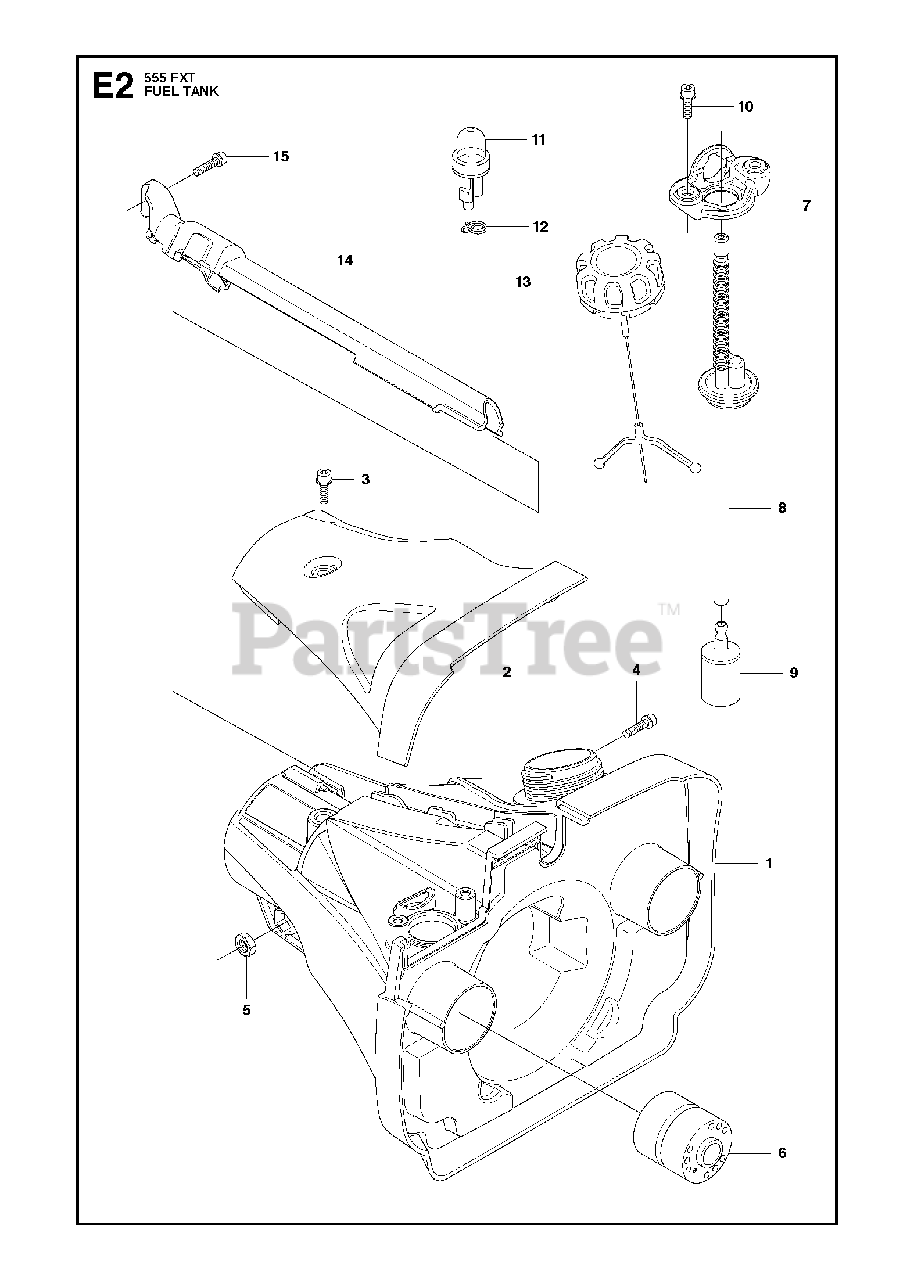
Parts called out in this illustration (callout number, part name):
2	COVER
3	SCREW IHSCFM
6	ANTIVIBE ELEMENT
9	FUEL FILTER
11	AIR PURGE BUBBLE
12	HOSE CLAMP
14	WIRING PROTECTION
15	SCREW IHSCFM
